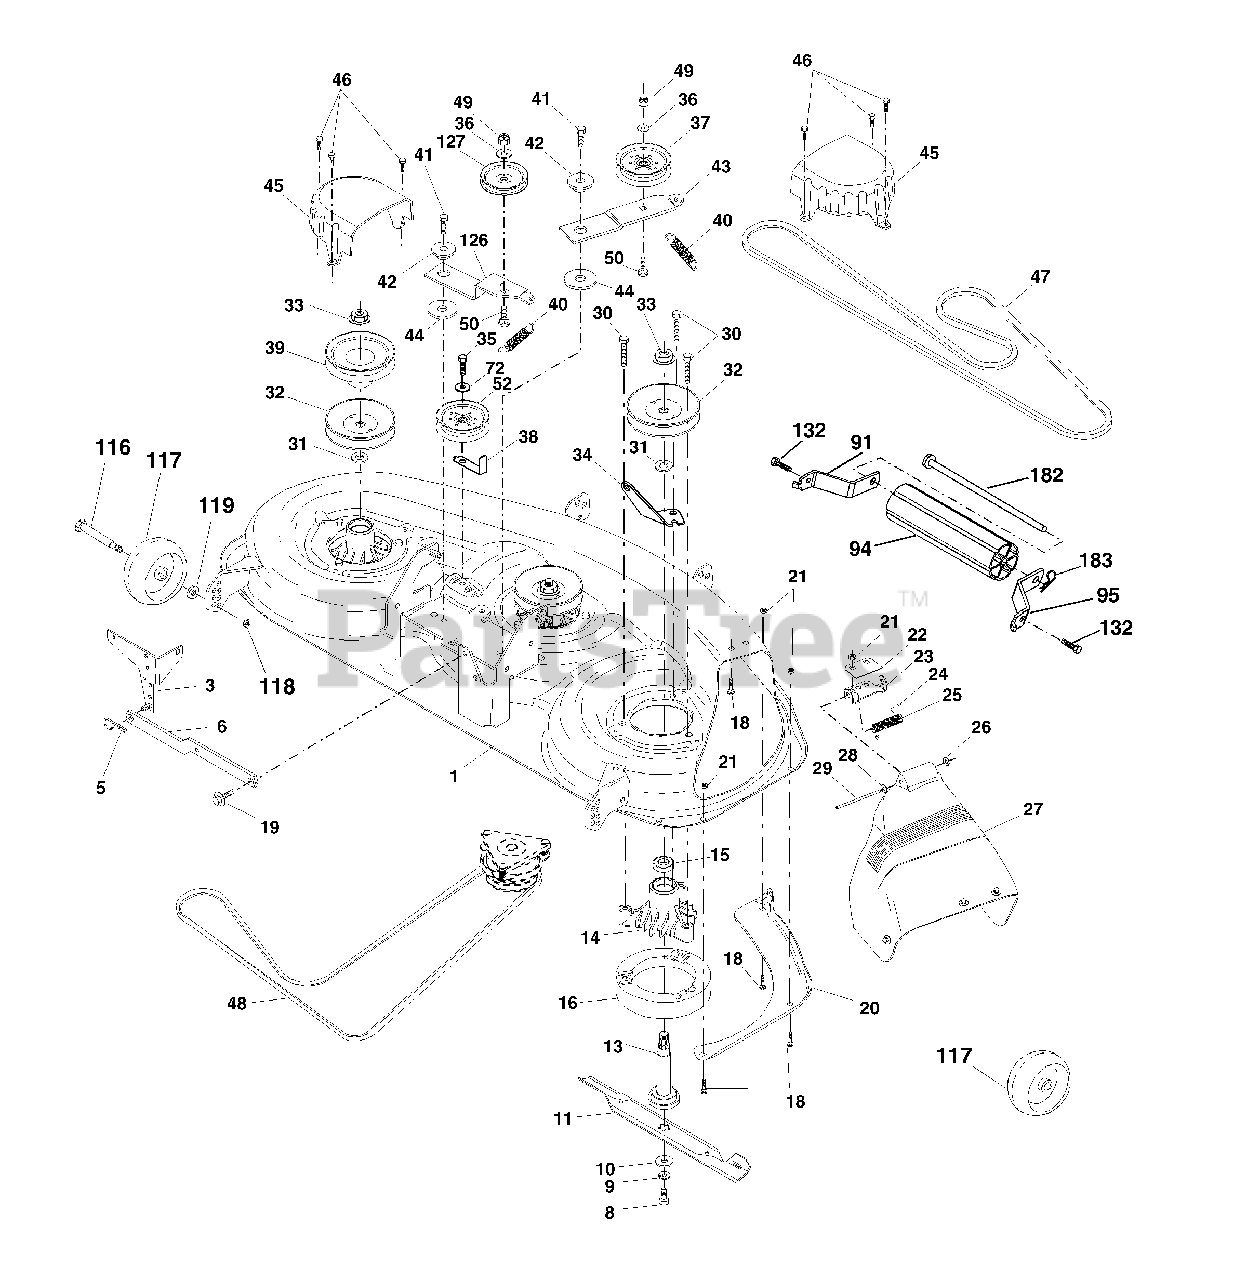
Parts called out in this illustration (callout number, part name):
1	Deck Weldment Mower HD 46 WID
3	Bracket Asm., Sway Bar
5	Retainer Spring
6	Bar Sway Deck
8	Bolt, Patched 3/8-24 x 1-1/4 Gr. 8
9	Washer, Lock Hvy., Unplated 3/8
10	Washer, Hard Blade, Mower Vented
11	Blade, 46" High Performance
11	Blade, 46" Mulching
13	Shaft Asm. w/Lower Bearing
14	Housing, Mandrel
15	Bearing, Ball, Mandrel
16	Stripper, Mower Round
18	Bolt, Carriage 5/16-18 x 5/8
19	Bolt, Hex Head, Shoulder 5/16-18
20	Baffle, Vortex Mower 46"
21	Nut, Crownlock 5/16-18 UNC
22	Stiffener, Bracket
23	Bracket, Deflector
24	Cap, Sleeve
25	Spring, Torsion, Deflector
27	Shield, Deflector Mower
28	Washer 11/32 x 5/8 x 16 Ga.
29	Rod, Hinge
30	Screw, Thdroll, Washer Head
31	Washer, Spacer Mower Vented
32	Pulley, Mandrel
33	Nut, Flg. Top Lock Cntr. 9/16
34	Anchor, Spring Deck 46"
35	Screw, Thdroll 3/8-16 x 1-3/4 Tytt
36	Washer 13/32 x 13/16 x 16 Ga.
37	Pulley, Idler, Flat
38	Keeper, Belt, Idler
39	Pulley, Idler, Driven
40	Spring, Secondary 44/46/50 Vent
41	Screw, Thdroll 3/8-16 x 1-1/4
42	Spacer, Retainer
43	Arm, Idler Secondary
44	Washer, Hardened
45	Cover, Mandrel Deck
46	Screw, Thdroll. 1/4-20 x 5/8
47	V-Belt, Mower, Secondary
48	V-Belt, Mower, Primary
49	Nut, Crownlock 3/8-16 UNC
50	Bolt, Carriage 3/8-16 x 1-1/2 Gr. 5
52	Pulley Idler Flat 46 Pri. Drive
72	Washer 13/32 x 1 x 16 Ga.
91	Bracket, Asm Noseroller, LH
94	Roller, Nose 38 & 42
95	Bracket, asm Noseroller RH
116	Bolt, Shoulder
117	Gauge Wheel
118	Nut, Centerlock 3/8-16 UNC
119	Washer 3/8 x 7/8 x 14 Ga.
126	Arm, Idler, Primary Deck 46"
127	Pulley, Idler, V-Groove Dim. 4.25
132	Screw 3/8-16 x .75
182	Rod Roller Nose
183	Retainer Spring
